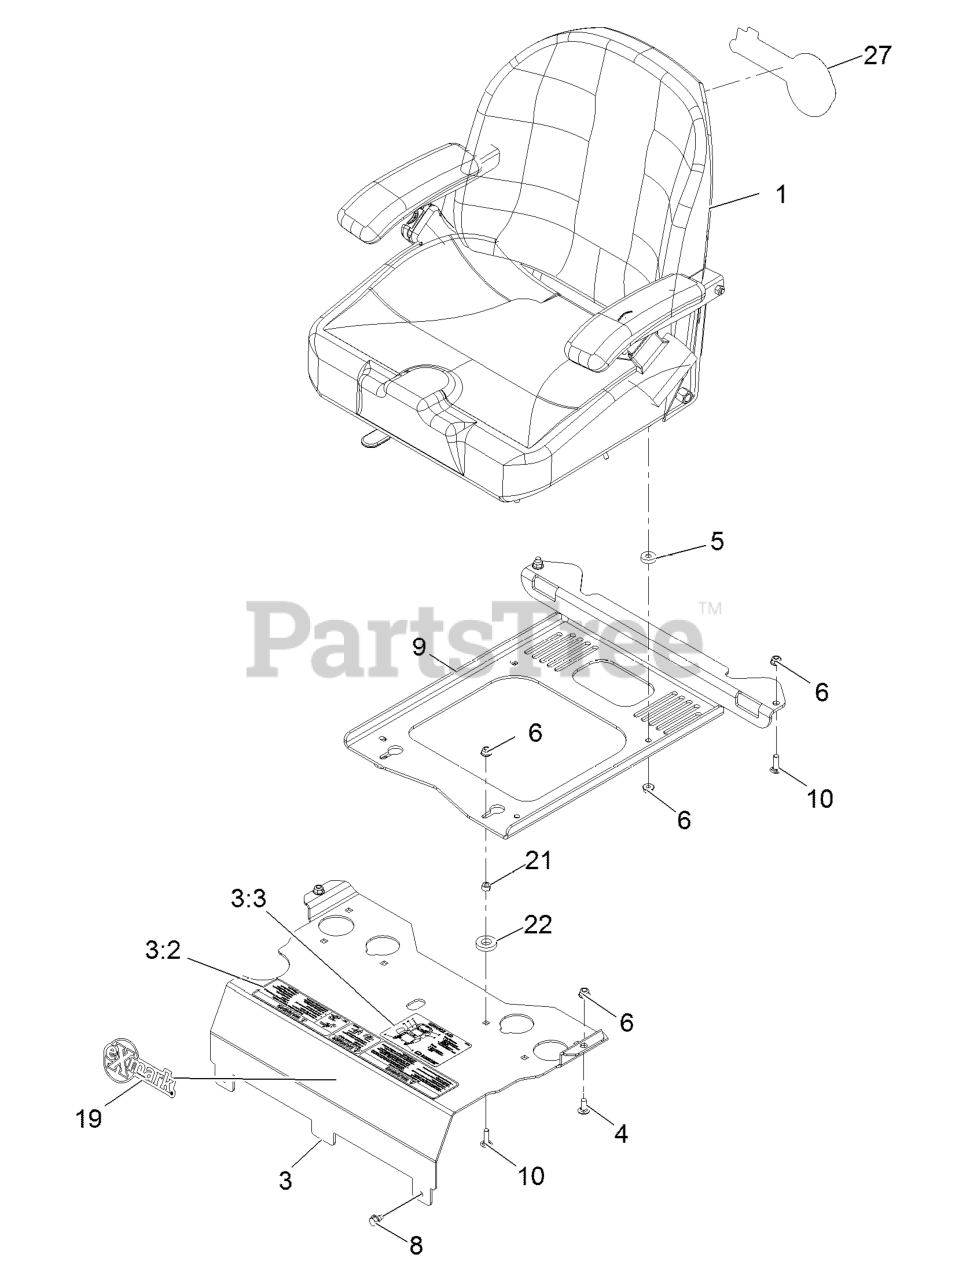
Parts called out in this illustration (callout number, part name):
1	ASM-SEAT, LZE
3	MOUNT-SEAT
3:2	DECAL-CONSOLE
3:3	DECAL-SERVICE AID
4	SCREW-CARR
6	NUT-HF, NI
9	PLATE-SUPPORT, SEAT
10	SCREW-CARR
21	NUT-HEX
27	DECAL,EXMARK LOGO
